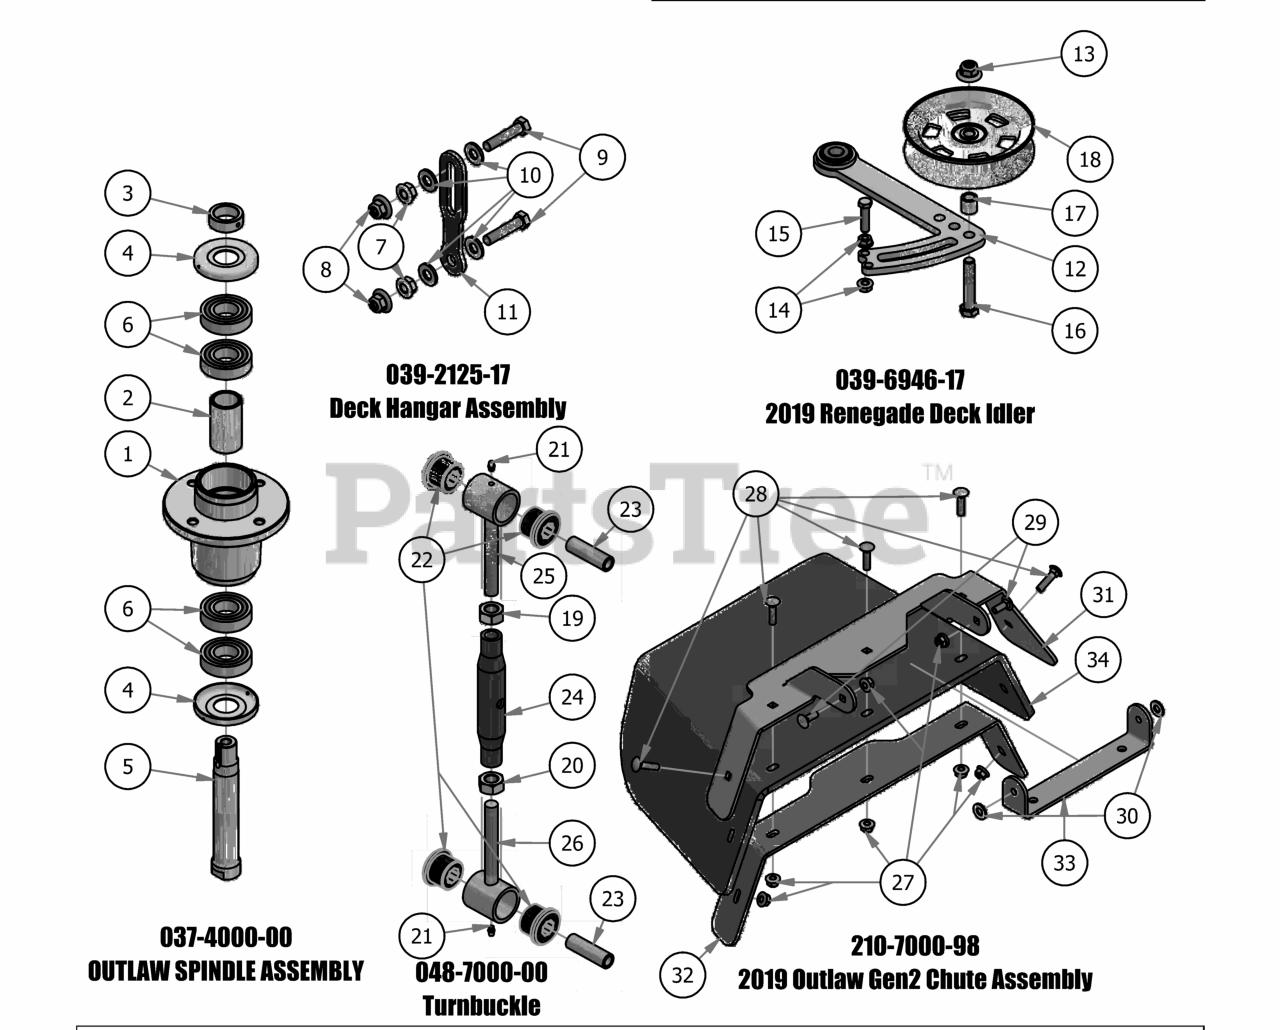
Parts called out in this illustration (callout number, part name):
1	4000 Series Spindle Housing
2	4000 Series Spindle Spacer
3	Locking Collar w/ 1/4"-20 Set Screw
4	Spindle Dust Cap
5	Spindle Shaft
6	Bearing - 6206
7	1/2" Flange Nut
8	1/2-13 Nylon Flange Nut
9	1/2-13X 2-1/4 GR Hex Bolts
10	.505 Nylon Spacer
11	Deck_Hanging_Tab
12	2019 Deck Tensioner
13	1/2-13 Nylon Flange Nut
14	3/8" Flange Nut
15	3/8 x 1.5" Bolt
16	1/2" x 2 3/4" Hex Bolt
17	Spacer 3/4 OD x 1/2 ID x 3\4 Length
18	5" Idler Pully
19	Hex Nut, 11/16-12
20	Hex Nut, 11/16-12 Left Handed
21	1/4" Press in Grease Fitting
24	2015 Outlaw Turnbuckle Body
25	2015 Outlaw Toplink RH End
26	Turnbuckle End Left-Handed Thread
27	5/16" Nylon Flange Nut
28	5/16" x 1 1/4" Carriage Bolt
29	5/16" x 7/8" Carriage Bolt
30	.360 ID Plastic Washer
31	2019 Upper Chute Bracket
32	2019 Lower Chute Bracket
33	2019 Chute Hanger
34	2019 Belted Chute with Logo
